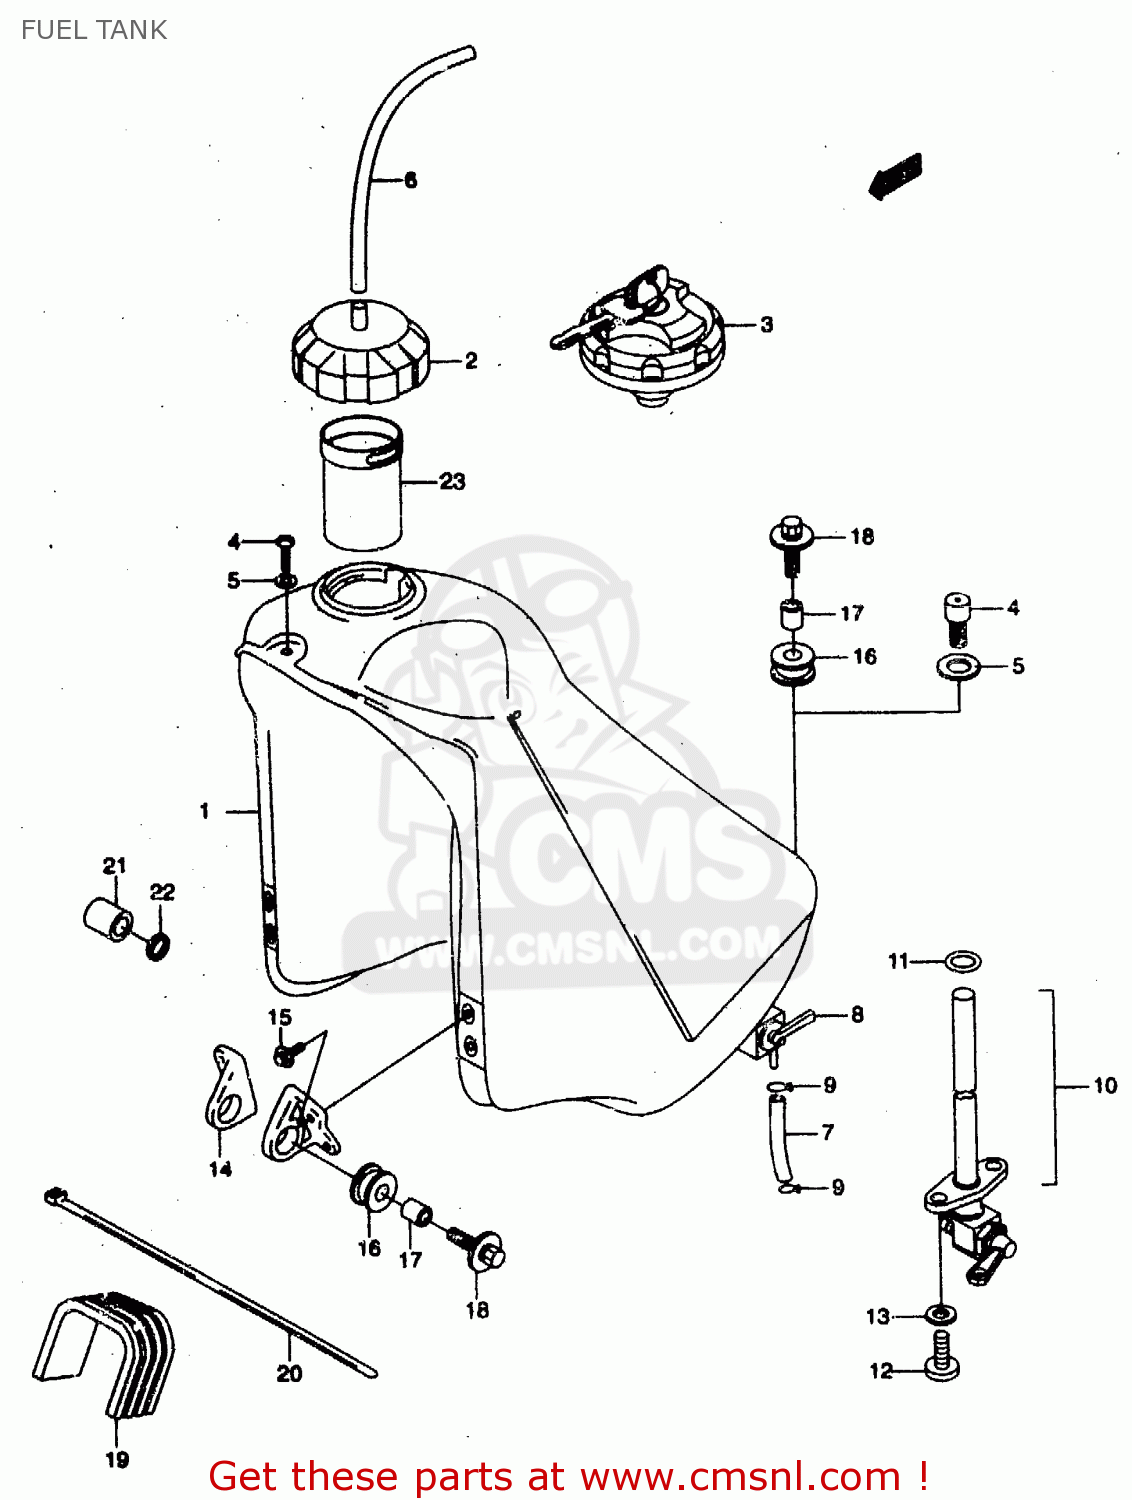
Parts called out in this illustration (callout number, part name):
1	TANK, FUEL
2	CAP, FUELTANK
3	CAP,FUELTANK
4	BOLT,OIL FILLE
5	WASHER(6.5X18X1.6)
6	HOSE, (L:260)
7	HOSE, FUEL (5X8.2X115)
8	COCK ASSY, FUEL
9	CLIP
10	COCK ASSY, FUEL
11	O RING
12	SCREW
13	LOCK WASHER
14	BRACKET,FUEL TANK FR
15	BOLT
16	CUSHION
17	SPACER
18	BOLT(8X30)
19	CUSHION
20	CLAMP(L:235)
21	CUSHION
22	WASHER
23	TUBE,FILLER IN
